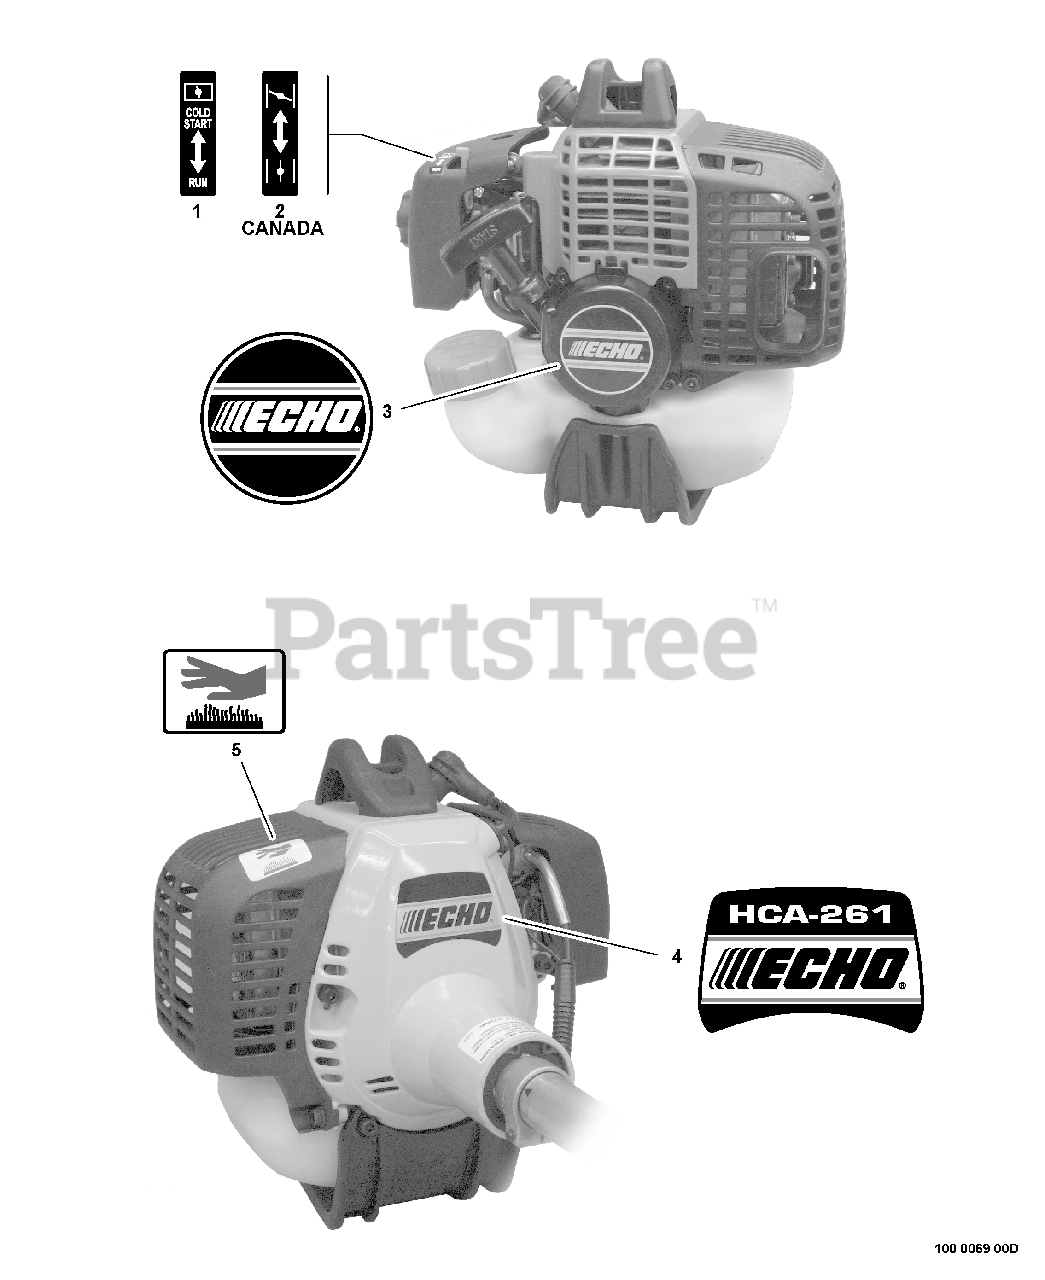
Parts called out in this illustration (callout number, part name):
1	LABEL - CHOKE
2	LABEL - CHOKE
3	LABEL - ECHO
4	LABEL - MODEL HCA-261
5	LABEL - HOT SURFACE
